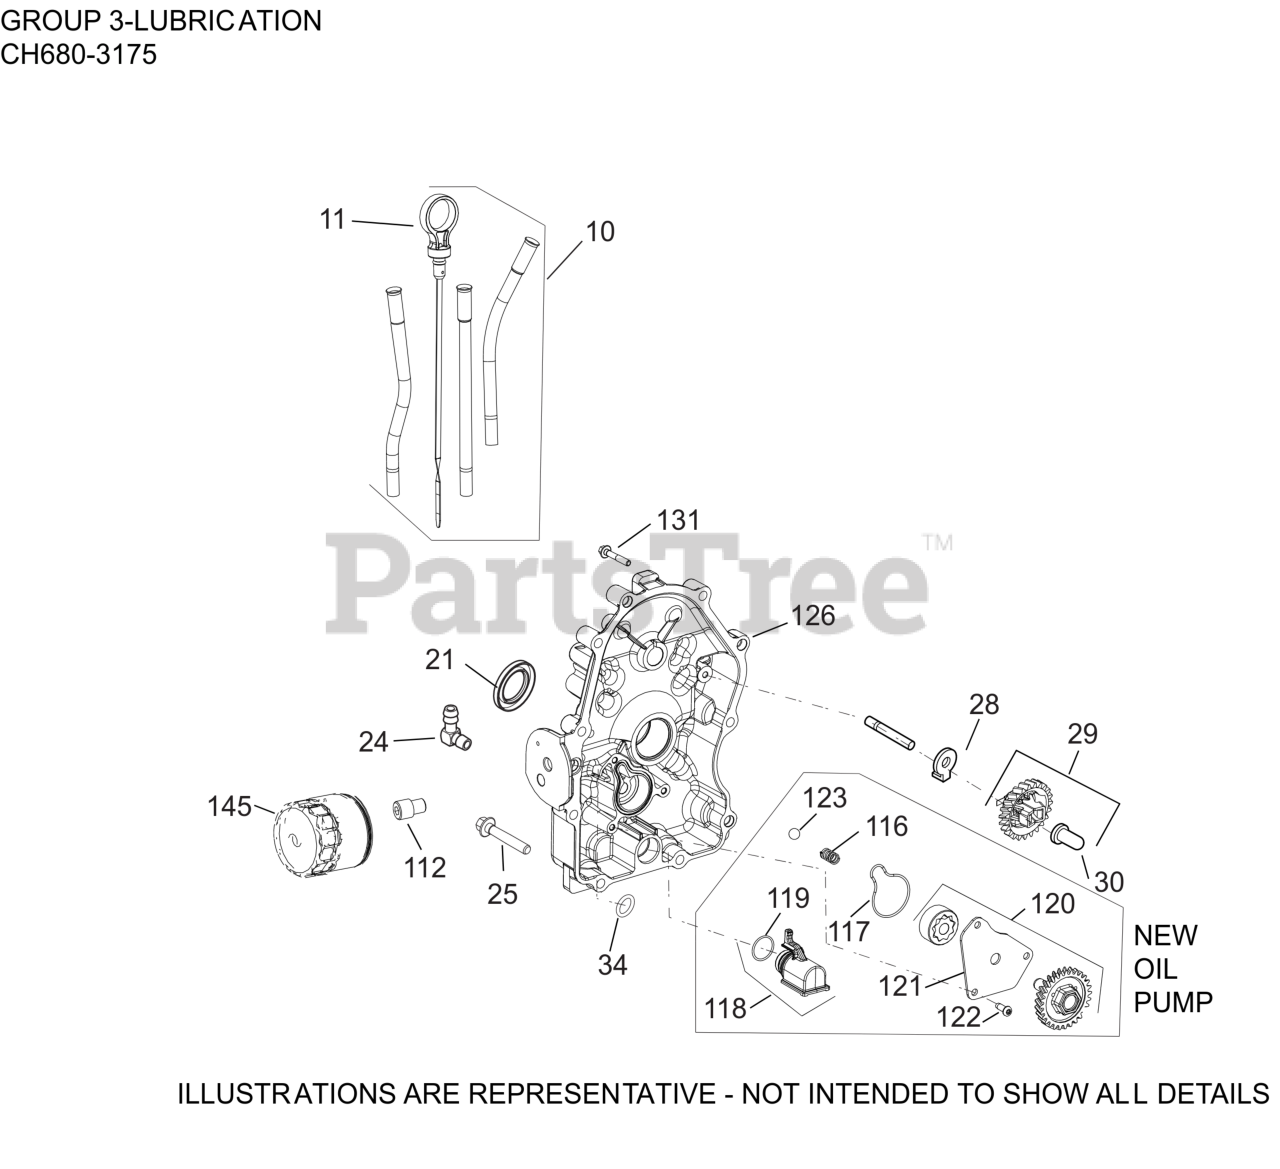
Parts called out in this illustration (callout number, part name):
10	KIT, DIPSTICK/DIPSTICK TUBES
24	CONNECTOR, 90 DEG. HOSE
25	SCREW, FLG M8X1.25X45
28	TAB, LOCKING
29	KIT, GOVERNOR GEAR W/PIN
30	PIN, GOVERNOR REGULATING
112	NIPPLE, OIL FILTER
116	SPRING, COMPRESSION
117	SEAL, OIL PUMP COVER
118	PICK-UP ASSEMBLY, OIL
119	O-RING, OIL PICK-UP
120	PUMP ASSEMBLY, OIL
121	COVER, OIL PUMP
122	SCREW, BUTTON HEAD
123	PRESSURE RELIEF BALL
126	CLOSURE PLATE ASSEMBLY (SERVICE)
131	SCREW, HEX FLANGE
145	FILTER, OIL EXTENDED LIFE
NI	SHAFT, GOVERNOR GEAR
